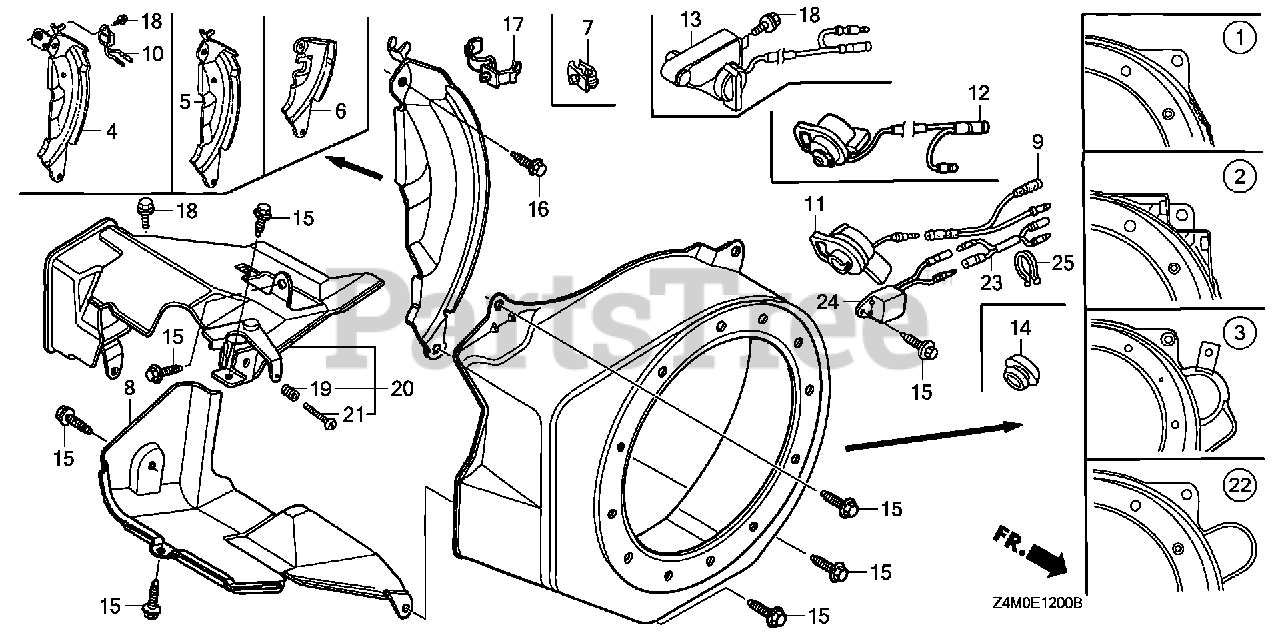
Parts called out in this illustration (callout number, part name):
1	COVER, FAN *NH1* (BLACK)
1	COVER, FAN *NH105* (MAT BLACK)
1	COVER, FAN *R280* (POWER RED)
4	PLATE, SIDE (OIL ALERT)
10	ALERT UNIT, OIL
12	SWITCH ASSY., ENGINE STOP (TOYO DENSO)
12	SWITCH ASSY., ENGINE STOP
15	BOLT, FLANGE (6X12) (CT200)
16	BOLT, FLANGE (6X20) (CT200)
17	CLIP, HARNESS
18	BOLT, FLANGE (6X8)
